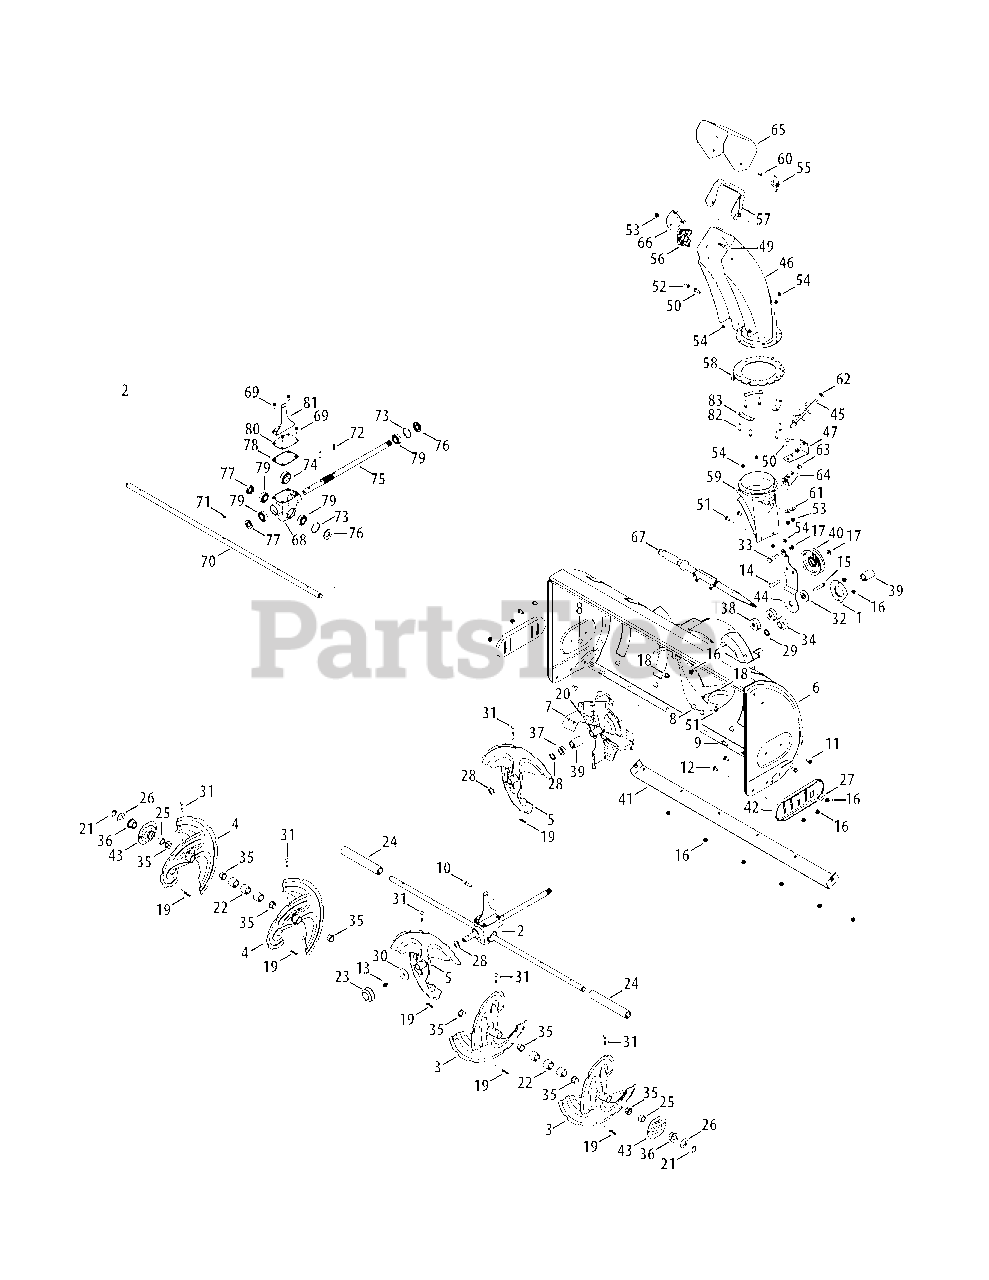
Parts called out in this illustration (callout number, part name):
1	Bearing Housing, 1.85
2	Auger Gearbox Assembly
3	LH Spiral Assembly
4	RH Spiral Assembly
5	Accel Asembly
7	Impeller Assembly
8	Carriage Bolt, 5/16-18 x .62
9	Carriage Screw, 5/16-18 x 1.00
10	Hex Screw, 5/16-18 x 1.00
11	Hex Washer Screw, 5/16-18 x .750
12	Carriage Bolt, 5/16-18 x .750
13	Hex Washer Screw, 5/16-18 x .500
14	Carriage Screw, 3/8-16 x 1.75
15	Hex Screw, 3/8-16 x 2.00
16	Flange Lock Nut, 5/16-18
17	Flange Lock Nut, 3/8-16
18	Flange Lock Nut, 3/8-16
19	Cotter Pin
20	Spiral Pin, .250 x 1.50
21	E-Ring, .750
22	Spacer, 1.25 x .75 x 1.00
24	Spacer, 1.25 x .75 x 7.805
25	Sleeve, .758 x 1.00 x .555
26	Flat Washer, .76 x 1.49 x .06
27	Flat Washer, .344 x 1.125 x .12
28	Flat Washer, .793 x 1.24 x .06
29	Flat Washer, .75 x 1.13 x .10
30	Flat Washer, .406 x 1.92 x .060
31	Shear Pin, .25 x 1.50
32	Shoulder Spacer, .8840 x .190
33	Shoulder Screw, 3/8-16 x .500 .875
34	Ball Bearing, .75 x 1.85
35	Flange Bearing, .800 x .910
36	Hex Flange Bearing, .75
37	Spacer, .766 x 1.25 x .415
38	Spacer, .385 x 1.75 x .585
39	Spacer, .76 x 1.25 x 1.8165
40	Idler Pulley, 3.50
43	Bearing Housing, 1.1605
44	Idler Pivot Bracket
45	Chute Crank Assembly, 6.25
46	Chute Assembly
47	Chute Crank Bracket
48	Chute Reinforcement
49	Carriage Bolt, 5/16-18 x 1.50
50	Carriage Screw, 5/16-18 x 1.00
51	Carriage Screw, 1/4-20 x .75
52	Hex Washer Screw, 1/4-15 x .750
53	Flange Lock Nut, 5/16-18
54	Flange Lock Nut, 1/4-20
55	Wing Knob, 5/16-18
56	Chute Tilt Cable Guide
57	Upper Chute Adapter
58	Chute Ring
59	Chute Adapter
60	Flat Washer, .349 x .879 x .063
61	Bell Washer, .340 x .872 x .060
62	Flat Washer, .406 x .875 x .059
63	Snap Flange Bearing, .385
64	Chute Crank Bracket
66	Cable Bracket
67	Snow Removal Tool
67	Snow Removal Tool Clip
68	Auger Housing, 500
69	Hex Washer Screw, 1/4-20 x .750
70	Auger Axle, .75 x 41.62
71	Hi-Pro Key, 3/16 X 5/8
72	Roll Pin, .25 x 1.00
73	Retainer Ring
74	Worm Gear, 20T
75	Worm Shaft, .75
76	Seal, .75 x 40 mm X .25
77	Seal, .75 x 1.375 x .25
78	Gearbox Cover Gasket
79	Ball Bearing, .750 x 40 x 12
80	Gearbox Cover, 500
81	Gearbox Support Bracket
82	Hex Screw, 1/4-20 x 1.00
83	Chute Flange Keeper Bracket
